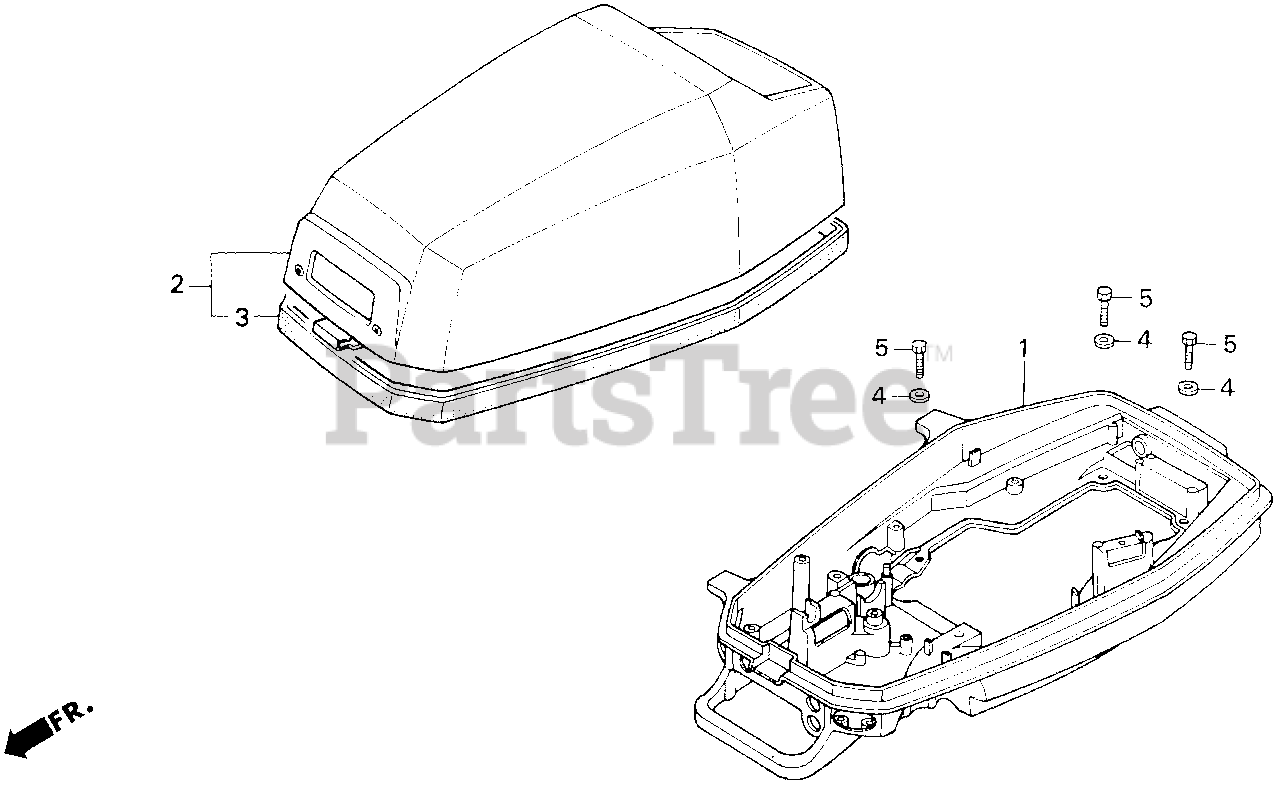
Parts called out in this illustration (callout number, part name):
1	CASE, ENGINE (LOWER) *NH282MU* (OYSTER SILVER METALLIC-U)
2	COVER, ENGINE *NH282MU* (OYSTER SILVER METALLIC-U)
3	SEAL, ENGINE COVER
4	WASHER, PLAIN (6MM)
5	BOLT, HEX. (6X16)
